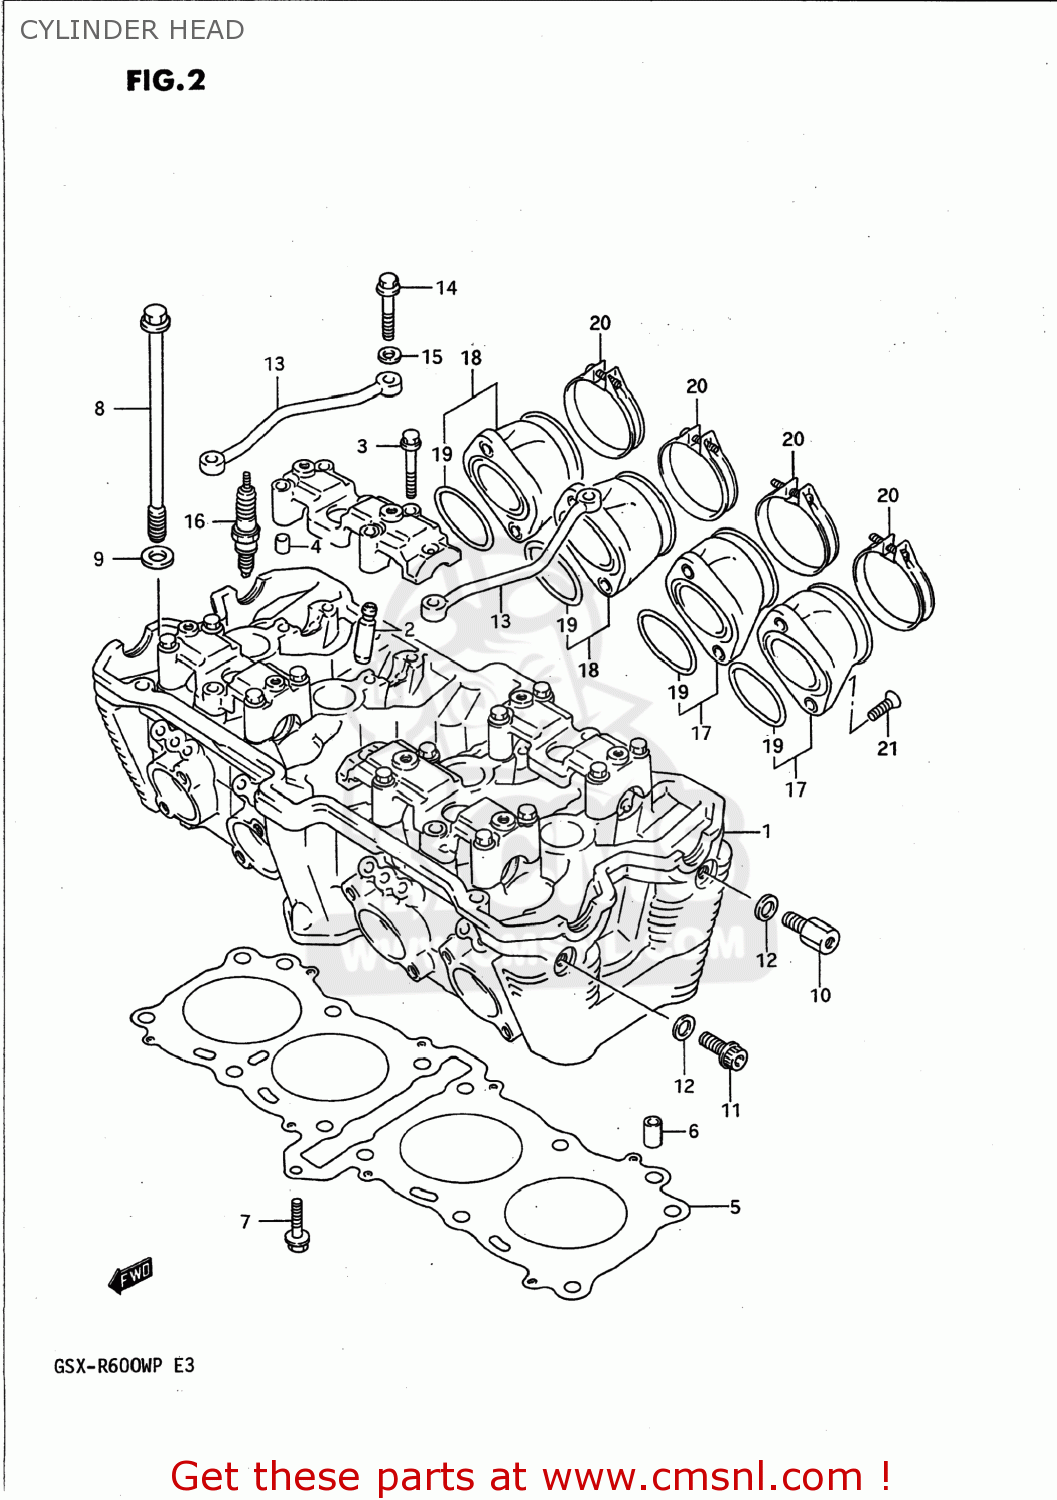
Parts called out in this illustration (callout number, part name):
1	HEAD ASSEMBLY,CYLINDER
2	GUIDE,VALVE
3	BOLT
4	PIN(6.2X8X11)
5	GASKET,CYLINDER HEAD
6	PIN
7	BOLT 6X30
8	BOLT(10X160)
9	WASHER(10.5X19X2)
10	BOLT 8X16
11	BOLT
12	GASKET(8.2X14X1).6 (NAS)
13	PIPE,CYLINDER HEAD OIL
14	BOLT(6X39)
15	WASHER
16	PLUG,SPARK(CR9EK)
17	PIPE ASSEMBLY,INTAKE NO.1
18	PIPE ASSEMBLY,INTAKE NO.2
19	O RING(D:2.4,ID:44)
20	CLAMP
21	SCREW(6X16)
